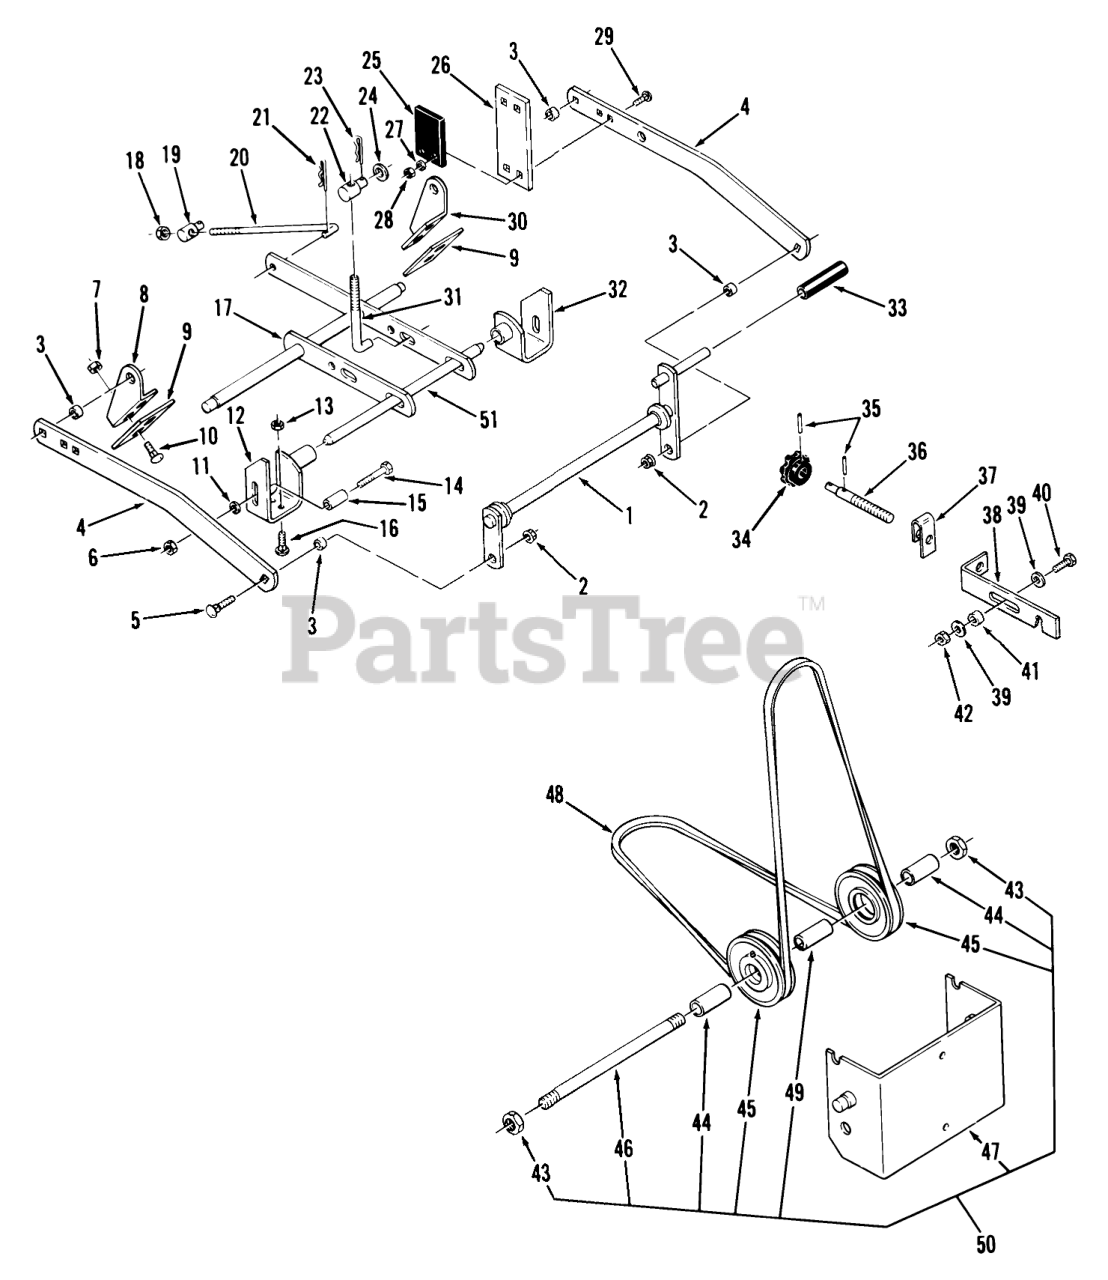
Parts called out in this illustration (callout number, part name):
1	Hitch Assy.
2	LOCKNUT-FLANGE
3	SPACER
4	Bar Draft
5	Bolt
6	Nut
7	Nut
8	Bracket-R.H.
9	PLATE
10	Bolt
11	WASHER
12	Bracket-RH Front
13	Nut
14	7/16-14X13/4 HEX BLT
15	SPACER-BEARING
16	Bolt-Carriage
17	Leveler Ass-y.
18	NUT
19	TRUNNION-LIFT
20	ROD-LEVELER
21	Hairpin
22	ROD-TRUNNION LIFT
23	Hairpin Cotter
24	Washer
25	BUMPER
26	PLATE-BUMPER R
27	Collar
28	Nut
29	Bolt-Carriage
30	Bracket-L.H.
31	LIFT ROD
32	LH FT DECK BRKT A R
33	GRIP
34	KNOB-ADJUSTMENT
35	PIN-ROLL
36	HITCH ADJ SCREW
37	Detent Spring
38	Hitch Adjustment Link
39	Washer
40	Bolt
41	SPACER
42	Nut
43	Nut
44	SPACER FRONT PULL R
45	Pulley-V
46	SHAFT FRONT PULLEY
47	Shield Assy.
48	V BELT
49	SPACER-FRONT PULLEY
50	S.A. Front Idler-Complete
51	SHAFT-FRONT R
